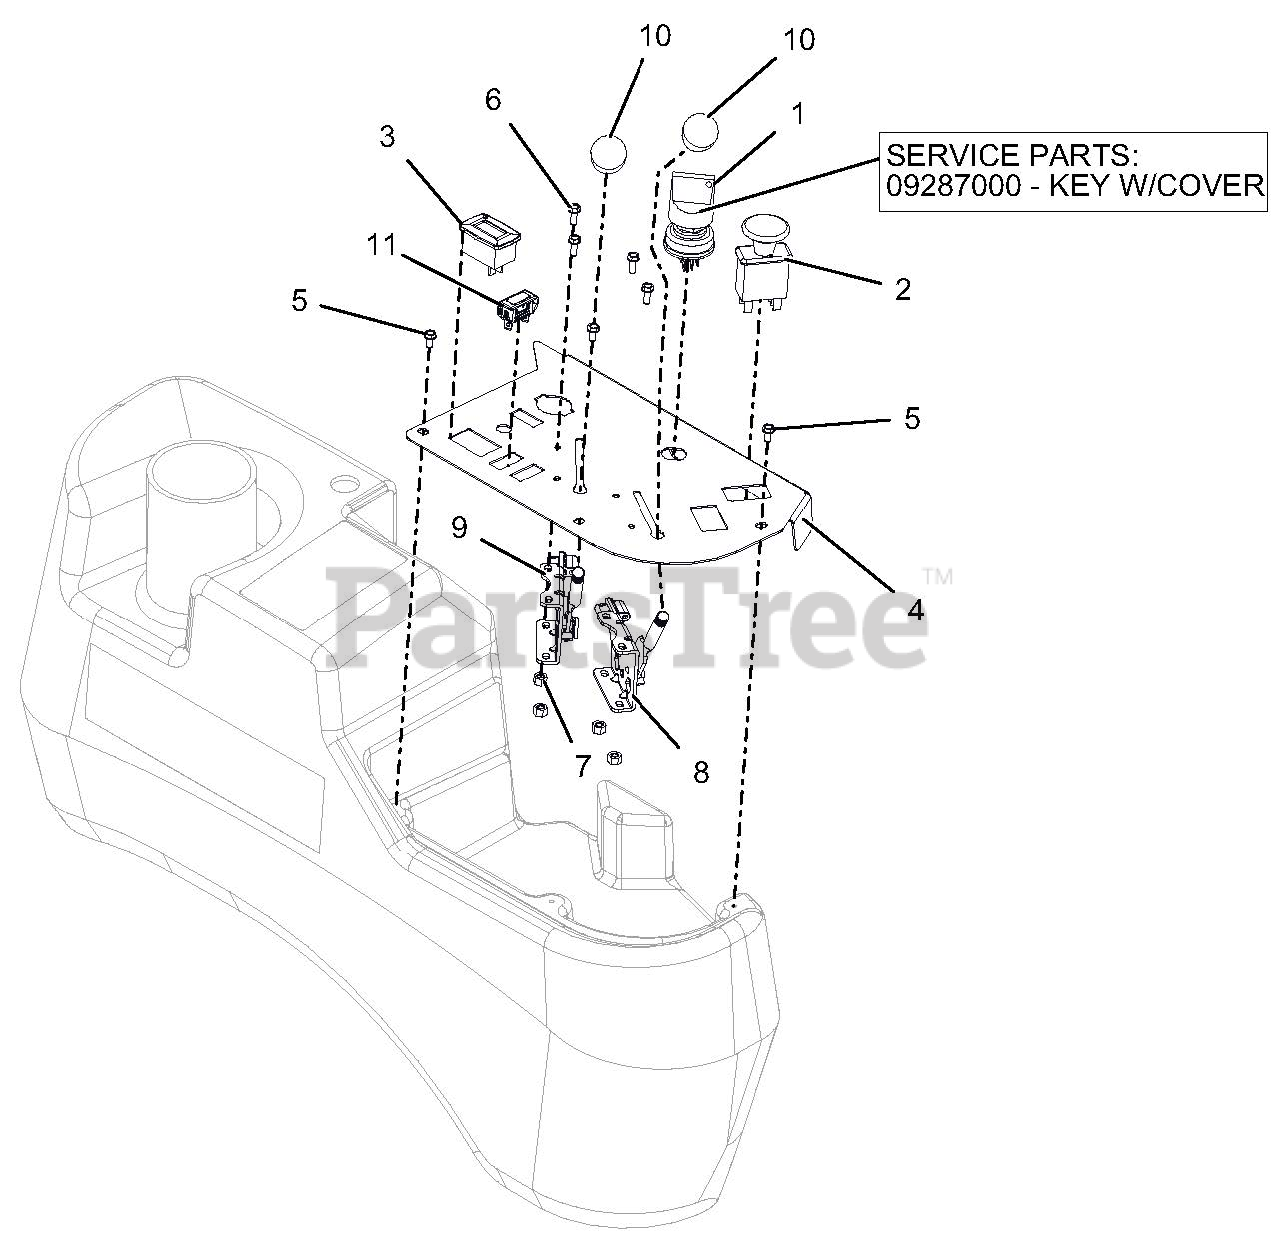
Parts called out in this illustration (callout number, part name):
1	SWITCH, IGNITION
1	KEY, W/ SHIELD
2	SWITCH, CLUTCH
3	METER, HOUR W/MAINTENANCE
4	PANEL, CONTROL - BLACK
5	SCR-MCH 10-24X.38 HWHSTAINLESS
6	@SCR-MCH 10-24X.50 HWH YWZC
7	@NUT-LK-NYL 10-24 W/INSRT YWZC
8	CABLE, PRO-CONTROL THROTTLE
9	CABLE, PRO-CONTROL
10	KNOB-CONTROL-BLACK .38-16X.50
11	LIGHT,INDICATOR
